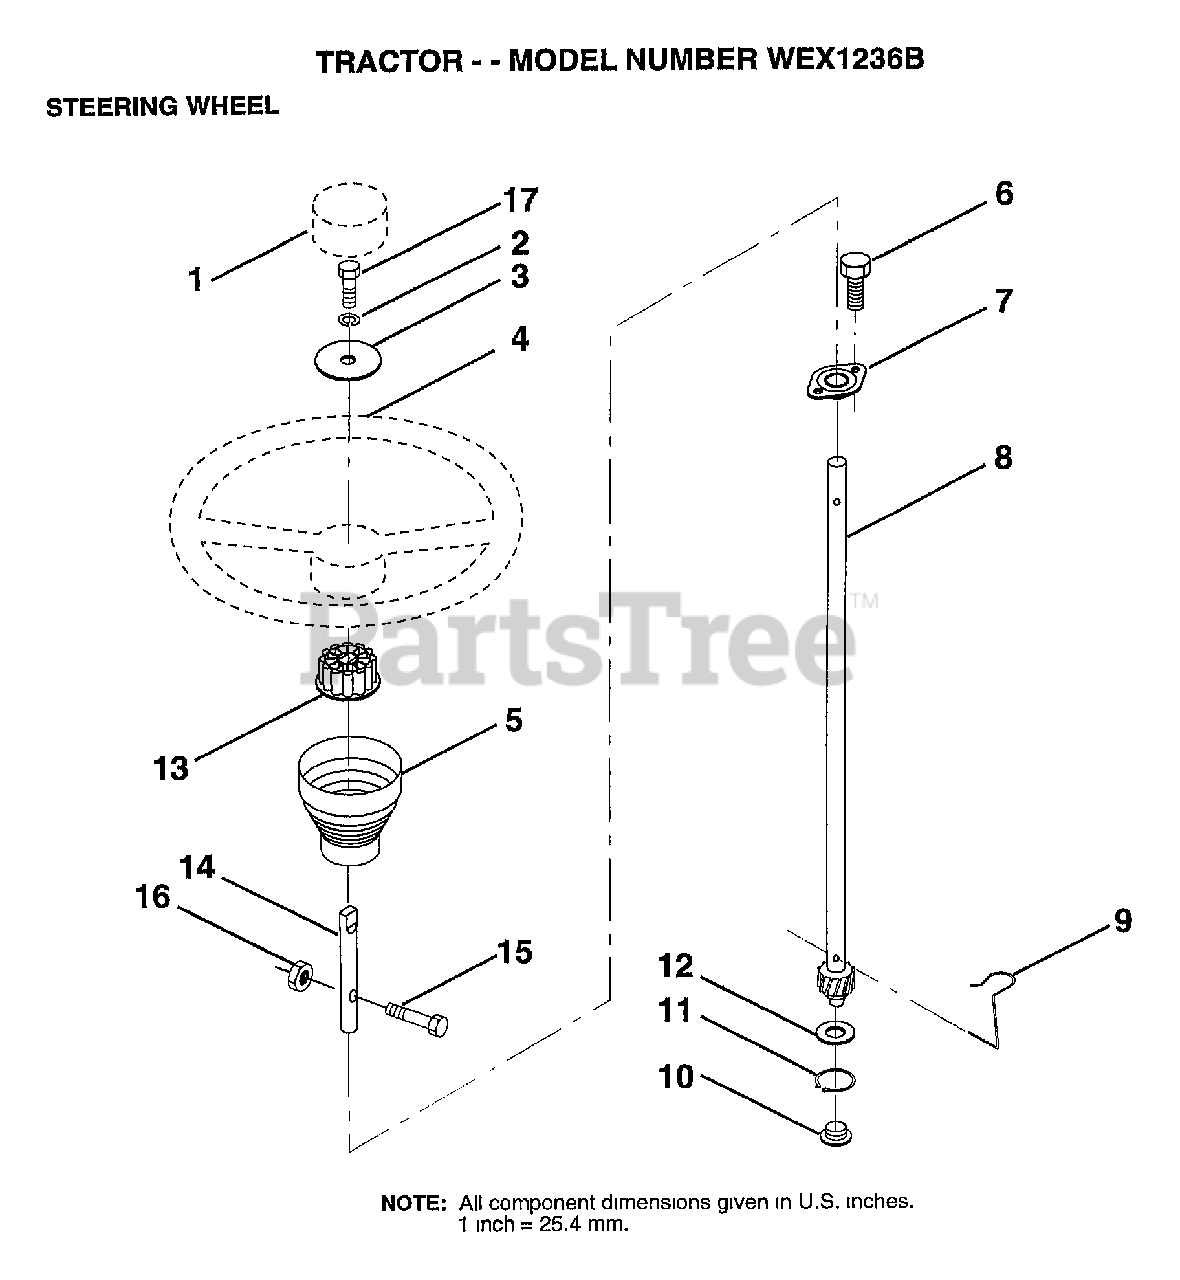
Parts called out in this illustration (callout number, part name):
1	ST WHL INSERT CAP
2	LOCKWASHER
3	WASHER T
5	SLEEVE STEERING
6	"SCREW-TT,10-32 FL"
7	BUSHING.STR.623
8	SHAFT.STEERING.LR
9	STEERING CLIP
10	BUSHING STEER LWR
11	RING
12	WASHER LT
13	ADAPTER LT
14	EXT SHAFT STEERIN
15	BOLT
16	NUT
17	BOLT
